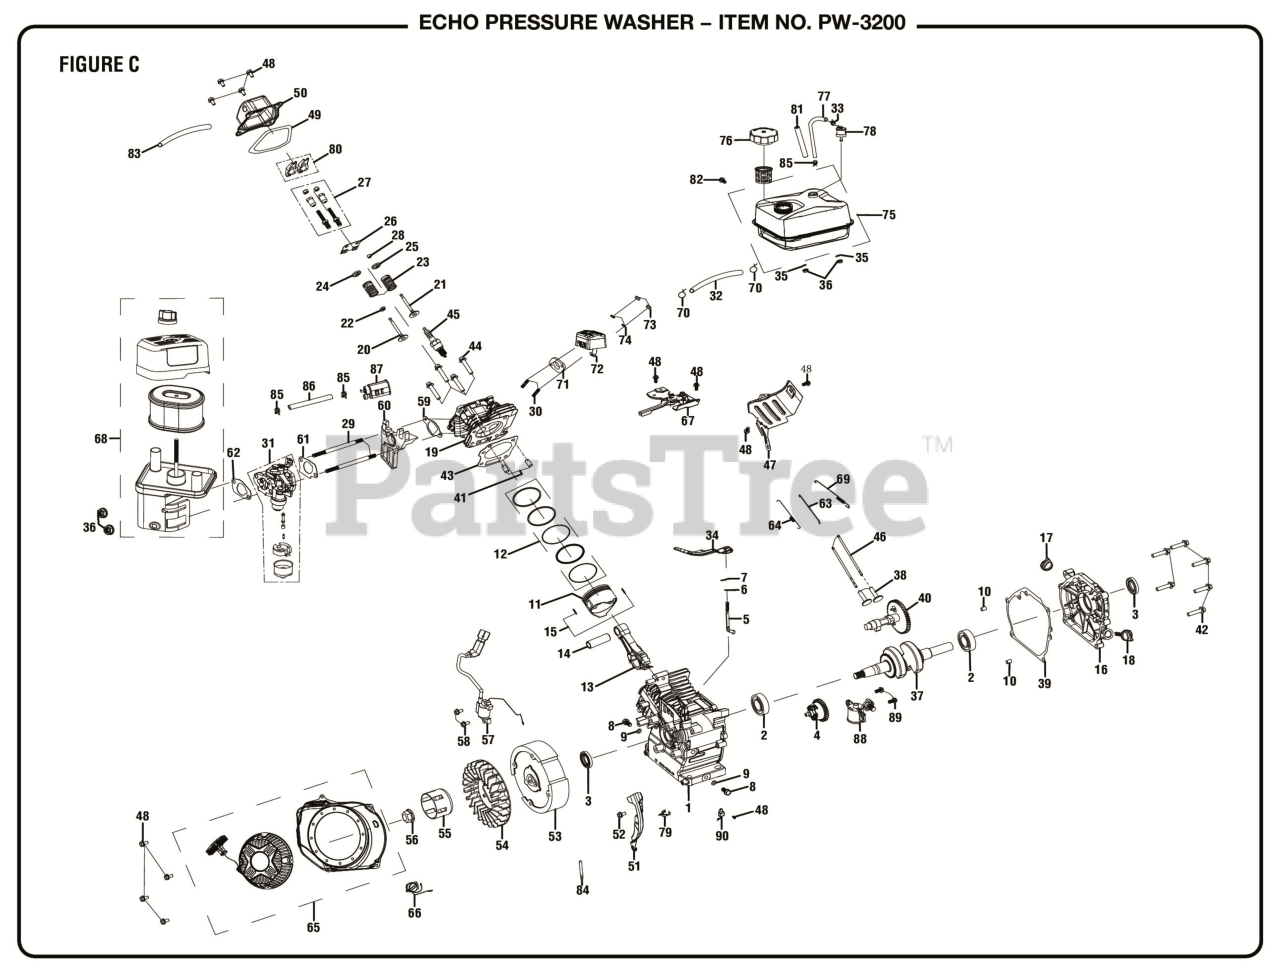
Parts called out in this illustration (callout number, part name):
1	CRANKCASE
2	BEARING, BALL
3	SEAL, OIL
4	ASSY., GOVERNOR
5	SHAFT, GOVERNOR ARM
7	PIN, LOCK
8	BOLT, DRAIN PLUG
9	WASHER, DRAIN PLUG
10	DOWEL PIN, CASECOVER
12	SET, PISTON SCRAPER RING
13	ASSY., CONNECTING ROD
14	PIN, PISTON
15	CLIP, PISTON
16	COVER, CRANKCASE
17	PLUG, OIL
18	DIPSTICK
19	CYLINDER HEAD
20	VALVE, INTAKE
21	VALVE, EXHAUST
22	RETURNER, INTAKE VALVE
23	SPRING,VALVE
24	SEAT, INTAKE VALVE SPRING
25	SEAT, EXHAUST VALVE SPRING
26	PLATE,PUSH ROD GUIDE
27	BOLT, ROCKER ARM
29	BOLT, STUD
30	BOLT, STUD
31	ASSY., CARBURETOR
32	HOSE, FUEL
33	CLIP, FUEL HOSE
34	ARM, GOVERNOR
37	ASSY., CRANKSHAFT
38	LIFTER, VALVE
39	GASKET, CRANKCASE COVER
40	ASSY., CAMSHAFT
41	PIN, DOWEL
43	GASKET, CYLINDER HEAD
45	PLUG, SPARK
46	ROD, PUSH
49	GASKET, VALVE COVER
50	COVER, VALVE
51	SHIELD, WIND
53	ASSY., FLYWHEEL
54	FAN, RECOIL STARTER
55	PULLEY, STARTER
57	MODULE, IGNITION
59	GASKET, INTAKE
60	INSULATOR, CARBURETOR
61	GASKET, CARBURETOR
63	ROD, GOVERNOR
64	SPRING, THROTTLE RETURN
65	ASSY., RECOIL STARTER
67	SHROUD, UPPER
68	AIR CLEANER
69	SPRING,GOVERNOR
70	CLIP, FUEL HOSE
71	GASKET, EXHAUST
74	WASHER, SPRING
75	ASSY., FUEL TANK
76	CAP, FUEL
77	PIPE, CONNECTING
78	ASSY., CHOKE
80	ARM, ROCKER
81	PROTECTOR, VENTILATION TUBE
83	TUBE, BREATHER
84	CLIP, WIRE HARNESS
85	CLIP, FUEL HOSE
86	PIPE, CONNECTING
87	CANNISTER, CARBON
88	SWITCH, OIL LEVEL
90	AMPLIFIER
